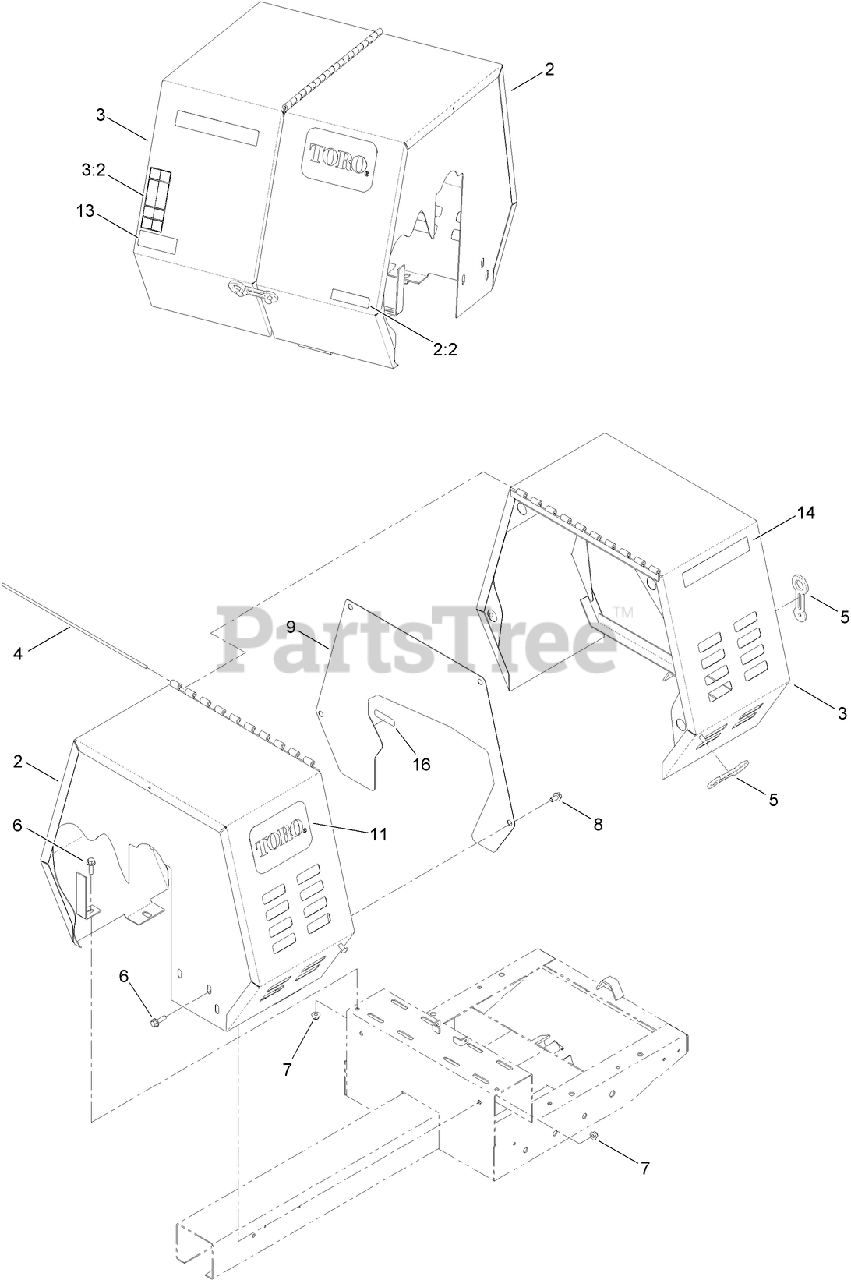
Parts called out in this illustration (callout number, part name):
2	STATIONARY COWL ASM
2:2	DECAL-ARRESTER, SPARK
3	MOVABLE COWL ASM
3:2	DECAL-WARNING
5	LATCH-RUBBER
6	SCREW-HHF
7	NUT-HF, NI
8	SCREW-HWH
9	PLATE-GUARD, BELT
11	DECAL
14	DECAL-MM-850E
16	DECAL-GREASE
